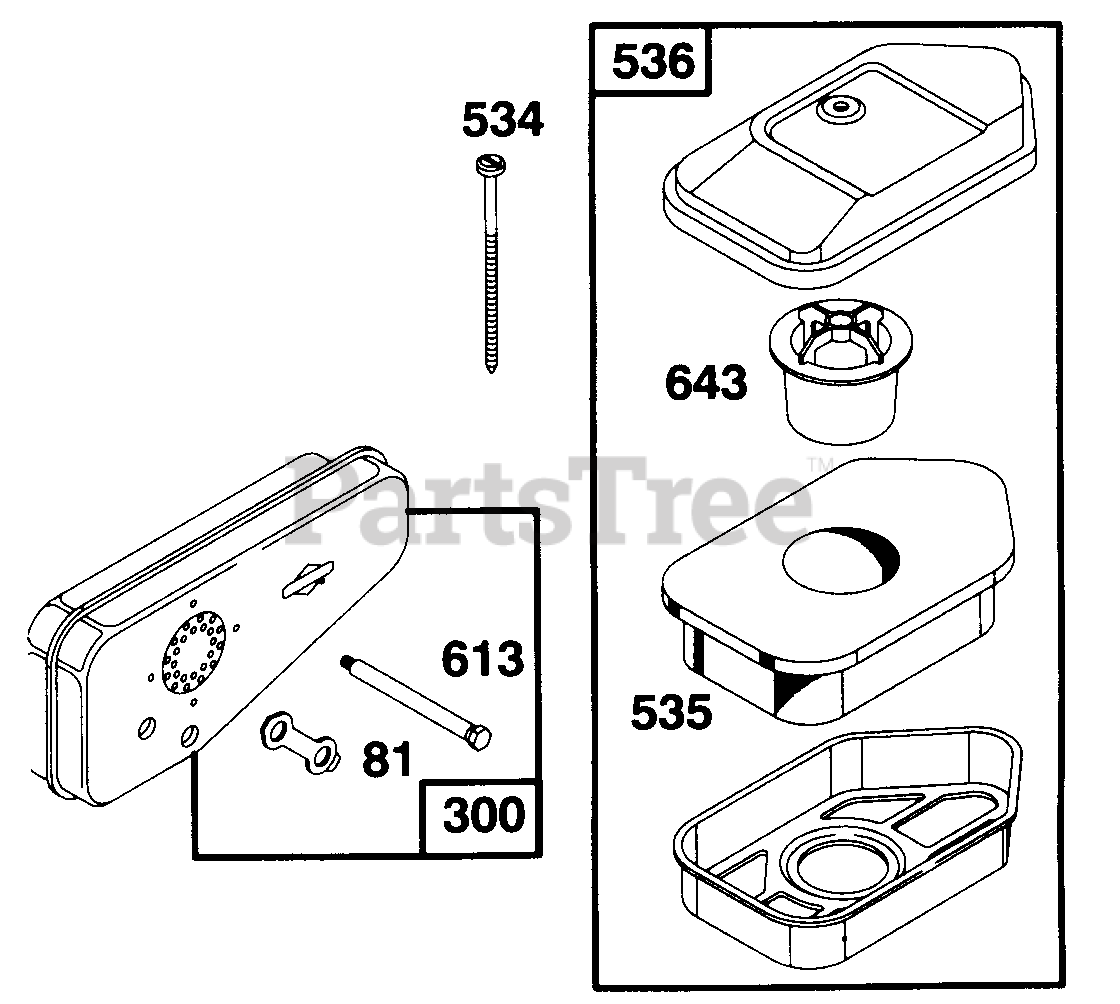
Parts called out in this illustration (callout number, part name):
81	Lock--Muffler Screw
300	Muffler--Exhaust
534	Screw--Air Cleaner
535	Element--Air Cleaner
536	Cleaner Assembly--Air
613	Screw--Hex Head
643	Cup--Air Cleaner
